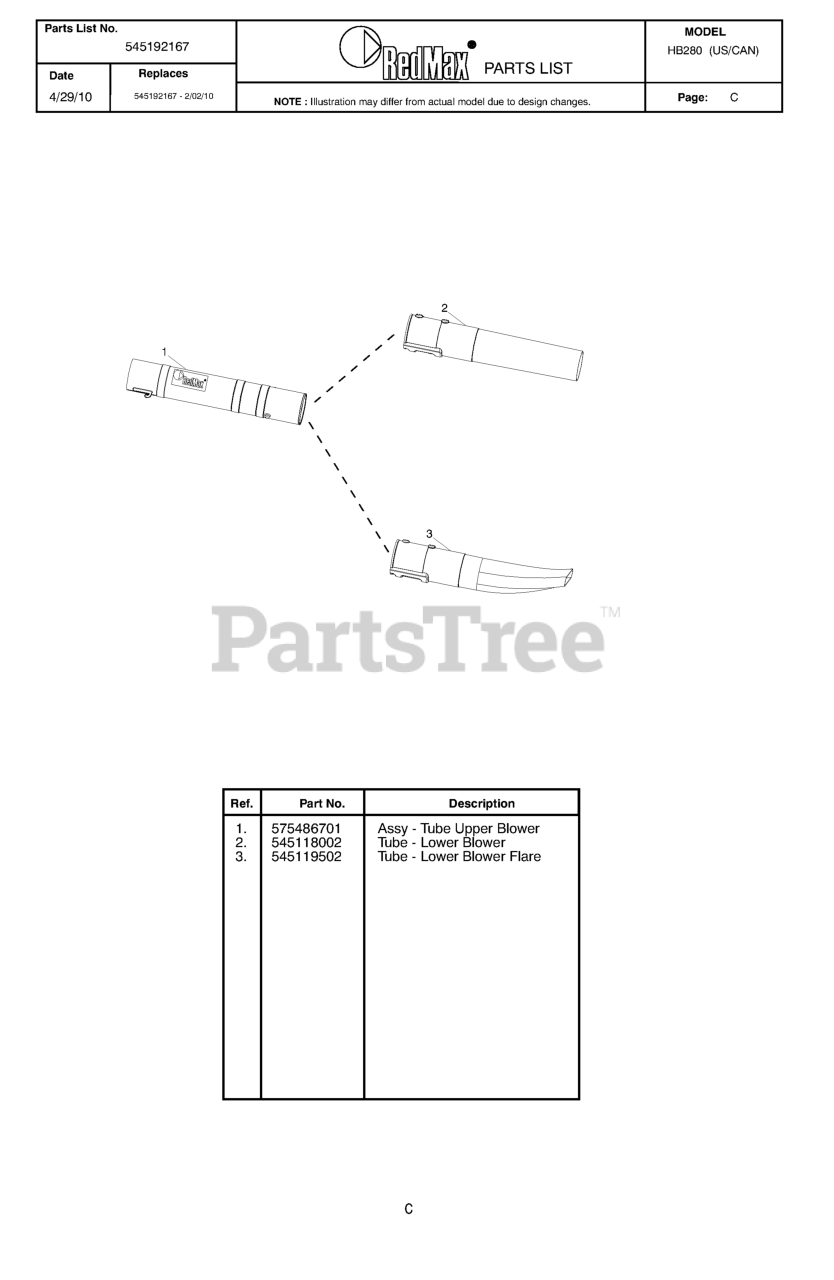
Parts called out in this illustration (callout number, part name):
1	TUBE UPPER BLOWER ASSY
2	TUBE - LOWER BLOWER
3	TUBE-LOWER BLOWER FLARE
